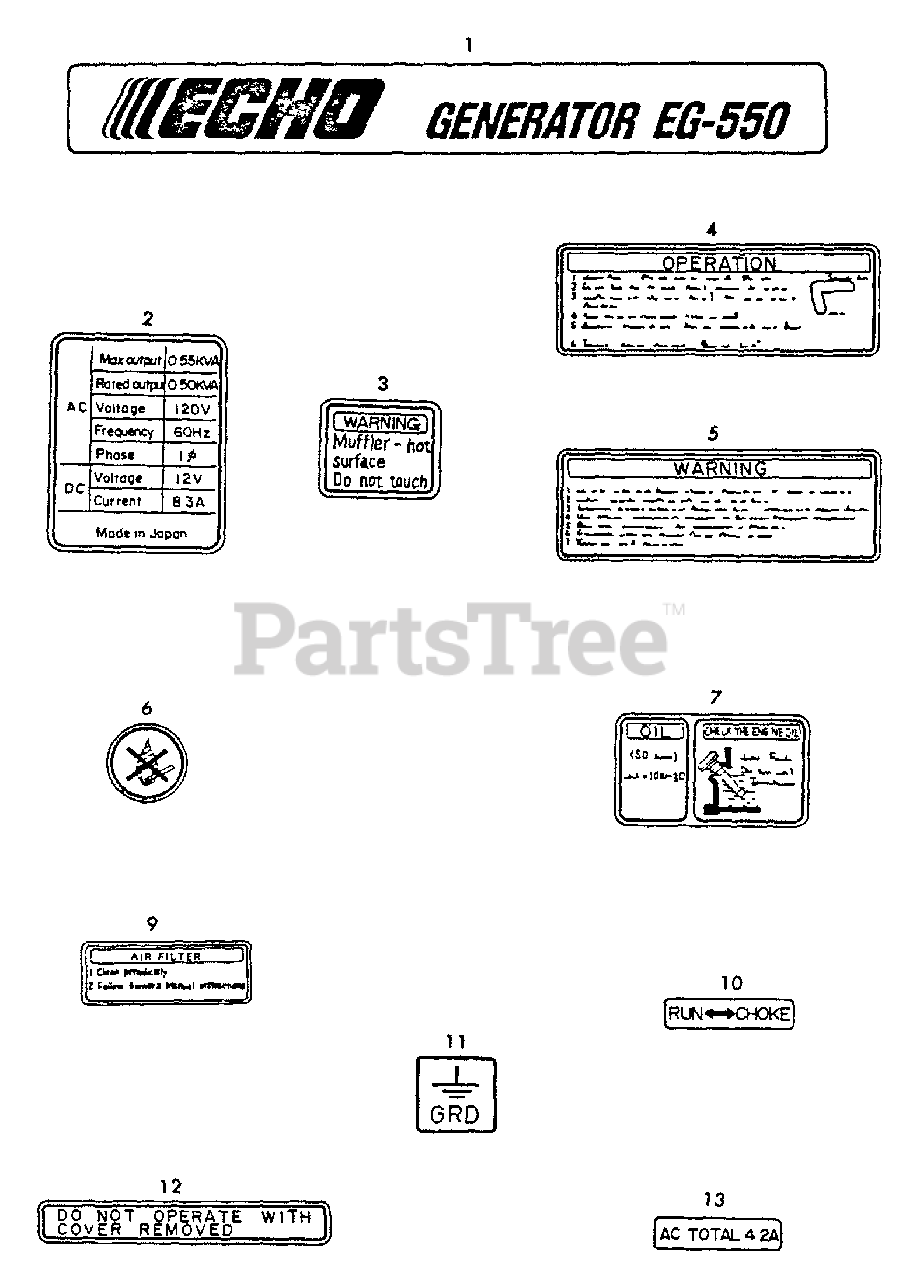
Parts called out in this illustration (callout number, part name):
1	LABEL - MODEL EG550
2	LABEL - GENERATOR
3	LABEL - CAUTION
4	LABEL - CAUTION -- OPERATION
5	LABEL - WARNING
6	LABEL, NON FIRE
7	LABEL, OIL
9	LABEL - AIR FILTER
10	LABEL - CHOKE
11	LABEL, EARTH
12	LABEL - CAUTION
13	LABEL, AMPERE
